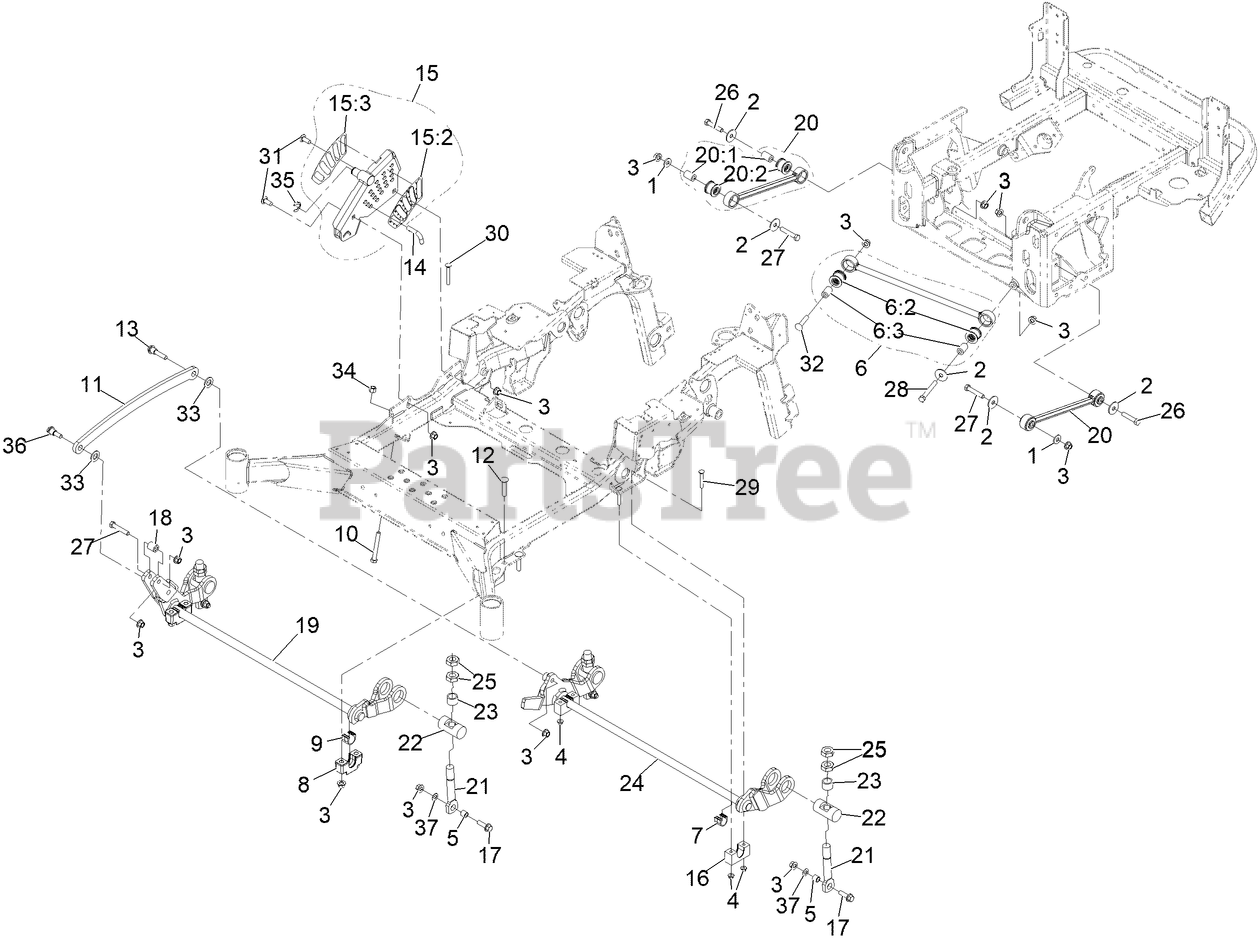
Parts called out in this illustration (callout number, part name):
1	WASHER-SPRING
2	WASHER-THRUST
3	NUT-LOCK
4	NUT-HF, NI
5	SPACER-PLAIN
6	PANHARD ROD ASM
6:2	BUSHING-SUSPENSION, RUBBER
6:3	SPACER
7	BEARING-CROSS SHAFT, REAR
8	SUPPORT-CROSS SHAFT, BEARING
9	BEARING-CROSS SHAFT, FRONT
10	BOLT-TAP
11	LINK-LIFT, DECK
12	BOLT-CARR
13	SCREW-HHF, SHOULDER
14	PIN-HOC
15	HOC ASM
15:2	DECAL-HEIGHT OF CUT
15:3	DECAL-HEIGHT OF CUT, OUTER
16	SUPPORT-CROSS SHAFT
17	SCREW-HHF
18	SPACER-PIVOT
19	DECKLIFT-FRONT, 144 [BLACK]
20	DECK STRUT ASM 85A
20:1	SPACER
20:2	BUSHING-RUBBER
21	LINK, DECK LIFT ADJUSTER
22	TRUNNION, DECK LIFT
23	SPACER, DECK LINK
24	WLD, DECK LIFT-REAR
25	NUT-HEX
26	SCREW-HH
27	SCREW-HH
28	SCREW-HH
29	SCREW-CARR
30	SCREW-CARR
31	SCREW-CARR, SHORT NECK
32	SCREW-CARR
33	WASHER-FLAT
34	NUT-LOCK, NI
35	RING-RETAINING
36	SCREW-SHOULDER, HHF
37	WASHER-ADJUSTING
